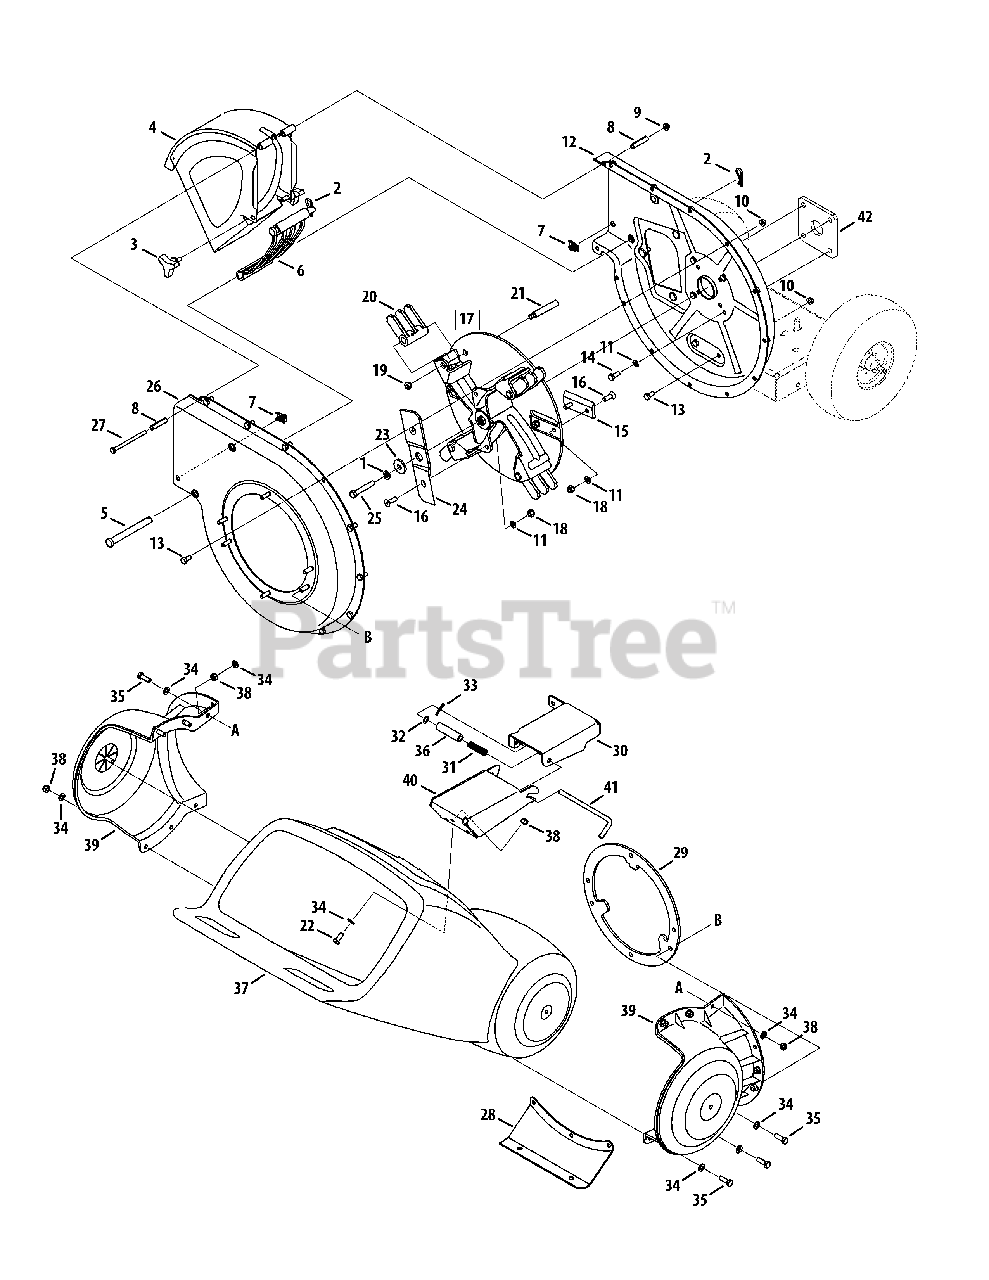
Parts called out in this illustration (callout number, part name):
1	Lock Washer, 3/8
2	Cotter Pin
3	Wing Knob 5/16-18
4	Chute Deflector Assembly
5	Clevis Pin
6	Shredder Screen
7	U-Nut 5/16-18
8	Spacer
9	Hex Lock Nut, 1/4-20
10	Hex Lock Nut 5/16-18
11	Lock Washer 5/16
12	Inner Impeller Housing Assembly
13	Hex Cap Screw 5/16-18 x .625
14	Hex Cap Screw 5/16-24 x 1.00
15	Chipper Blade (standard)
15	Chipper Blade (premium)
16	Hex Cap Screw 5/16-24 x 1.0
17	Impeller Assembly (standard)
17	Impeller Assembly (premium)
18	Hex Lock Nut 5/16-24
19	Nut, Jam Lock, 3/8-16
20	Flail Blade
21	Shoulder Pin, .5 x 2.625
22	Hex Cap Screw 5/16-18 x .75
23	Flat Washer 3/8 x 1.25
24	Shredder Blade
25	Hex Cap Screw 3/8-24 x 2.25
26	Outer Impeller Housing Assembly
27	Hex Cap Screw 1/4-20 x 3.75
28	Front Support Bracket
29	Shredder Plate
30	Rear Hopper Bracket Assembly
31	Compression Spring 1.75
32	Flat Washer
33	Cotter Pin
34	Flat Washer .330 ID x. 630 OD
35	Hex Cap Screw 5/16-18 x 1.0
36	Spacer,.375 ID x 2.50 LG
37	Hopper Assembly
38	Hex Lock Nut 5/16-18
39	Hopper Collar
40	Front Hopper Bracket Assembly
41	Lock Rod
42	Engine Plate
